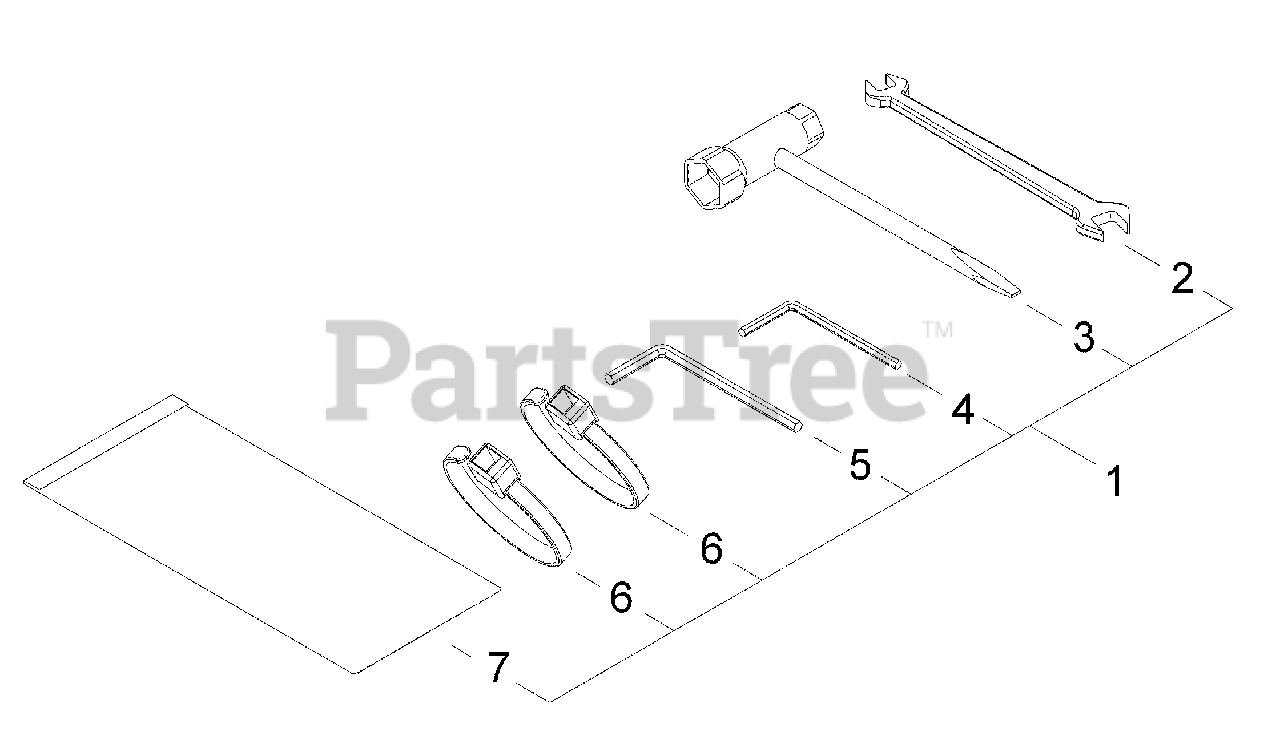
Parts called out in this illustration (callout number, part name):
1	TOOL KIT, SERVICE
2	SPANNER 8×10
3	T-WRENCH 16×13
4	WRENCH, ALLEN 4 MM
5	WRENCH, ALLEN 5 MM
6	TIE, CABLE
7	BAG, TOOL
